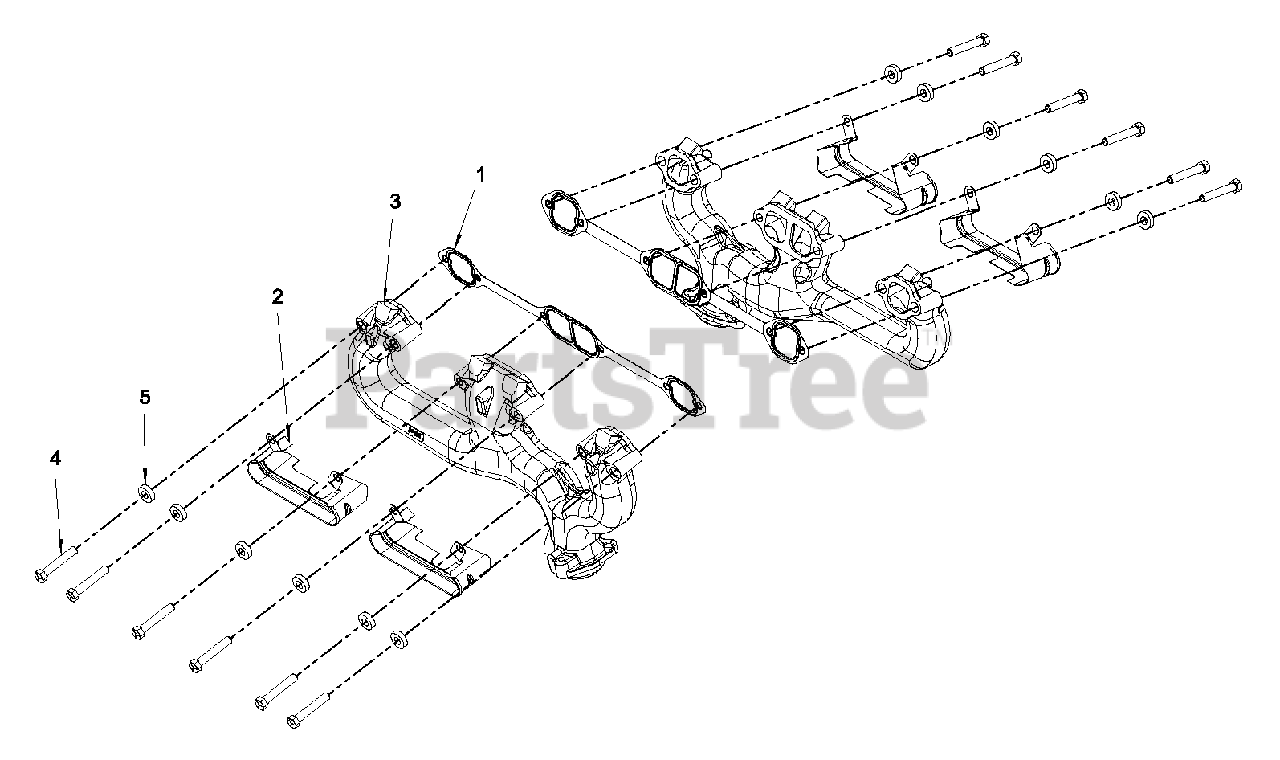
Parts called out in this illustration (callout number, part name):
2	* HEAT SHIELD
3	* EXHAUST MANIFOLD
4	* BOLT
5	* WASHER
